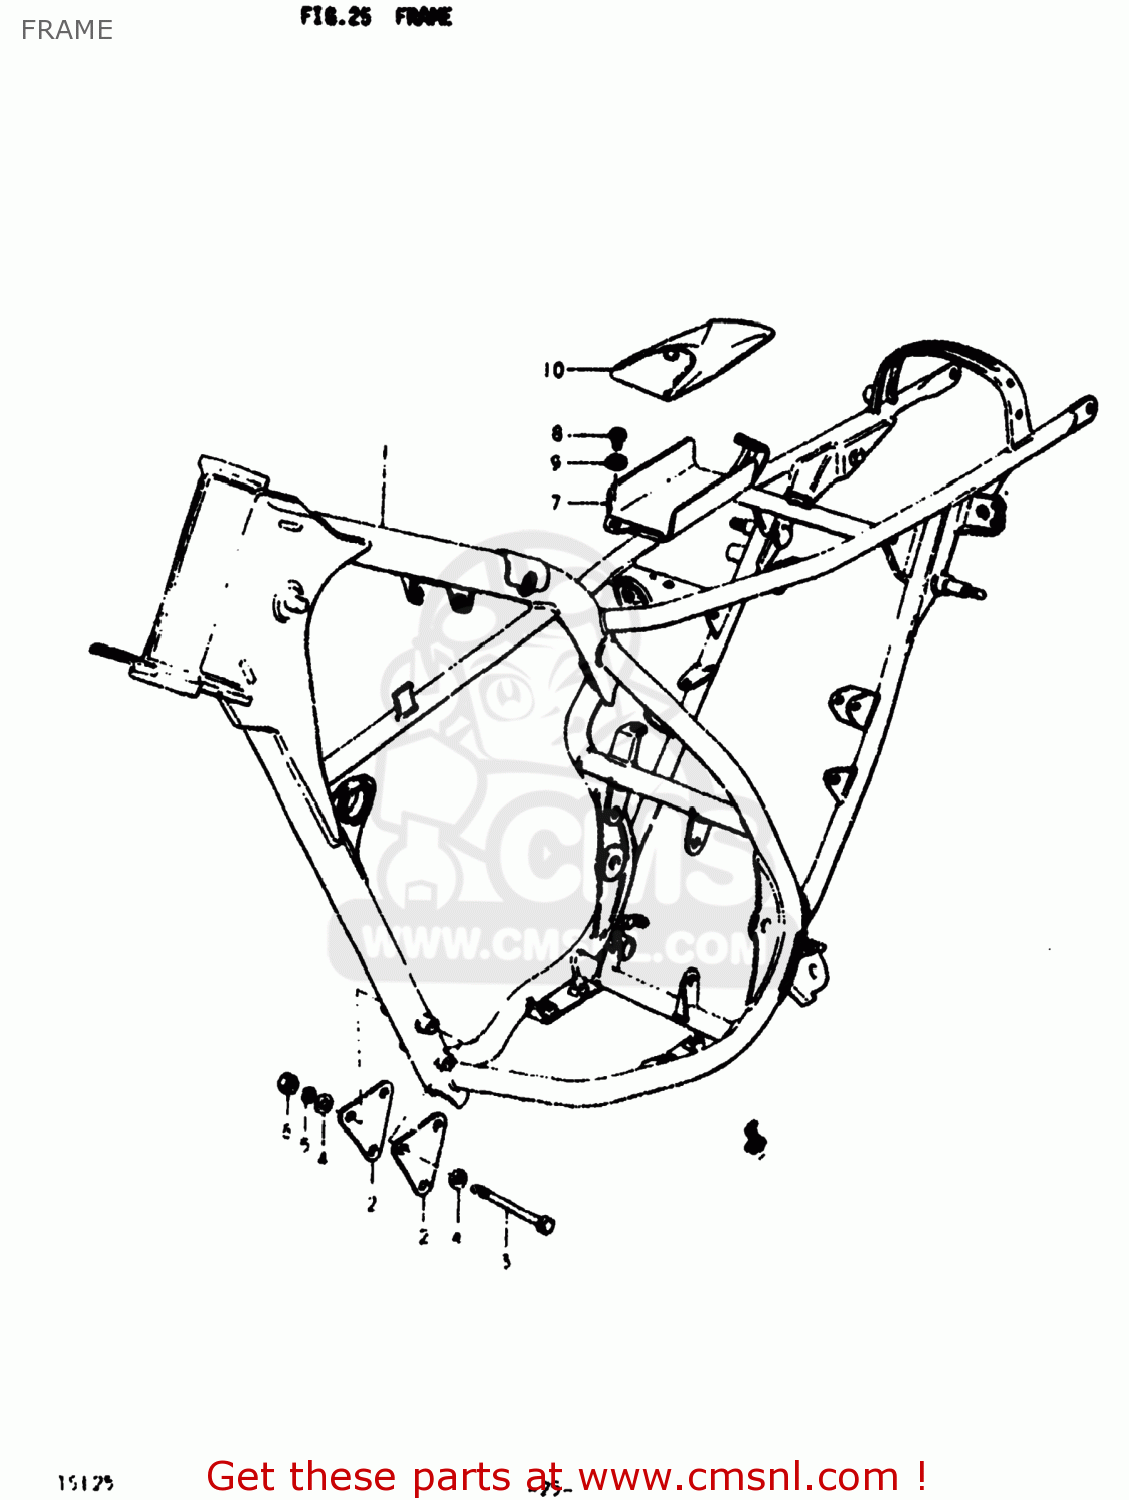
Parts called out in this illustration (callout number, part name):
1	FRAME
2	PLATE,ENG MTG
3	BOLT,8X75
4	WASHER
5	LOCK WASHER
6	NUT
7	HOLDER,TOOL
8	SCREW
9	WASHER
10	TOOL SET
